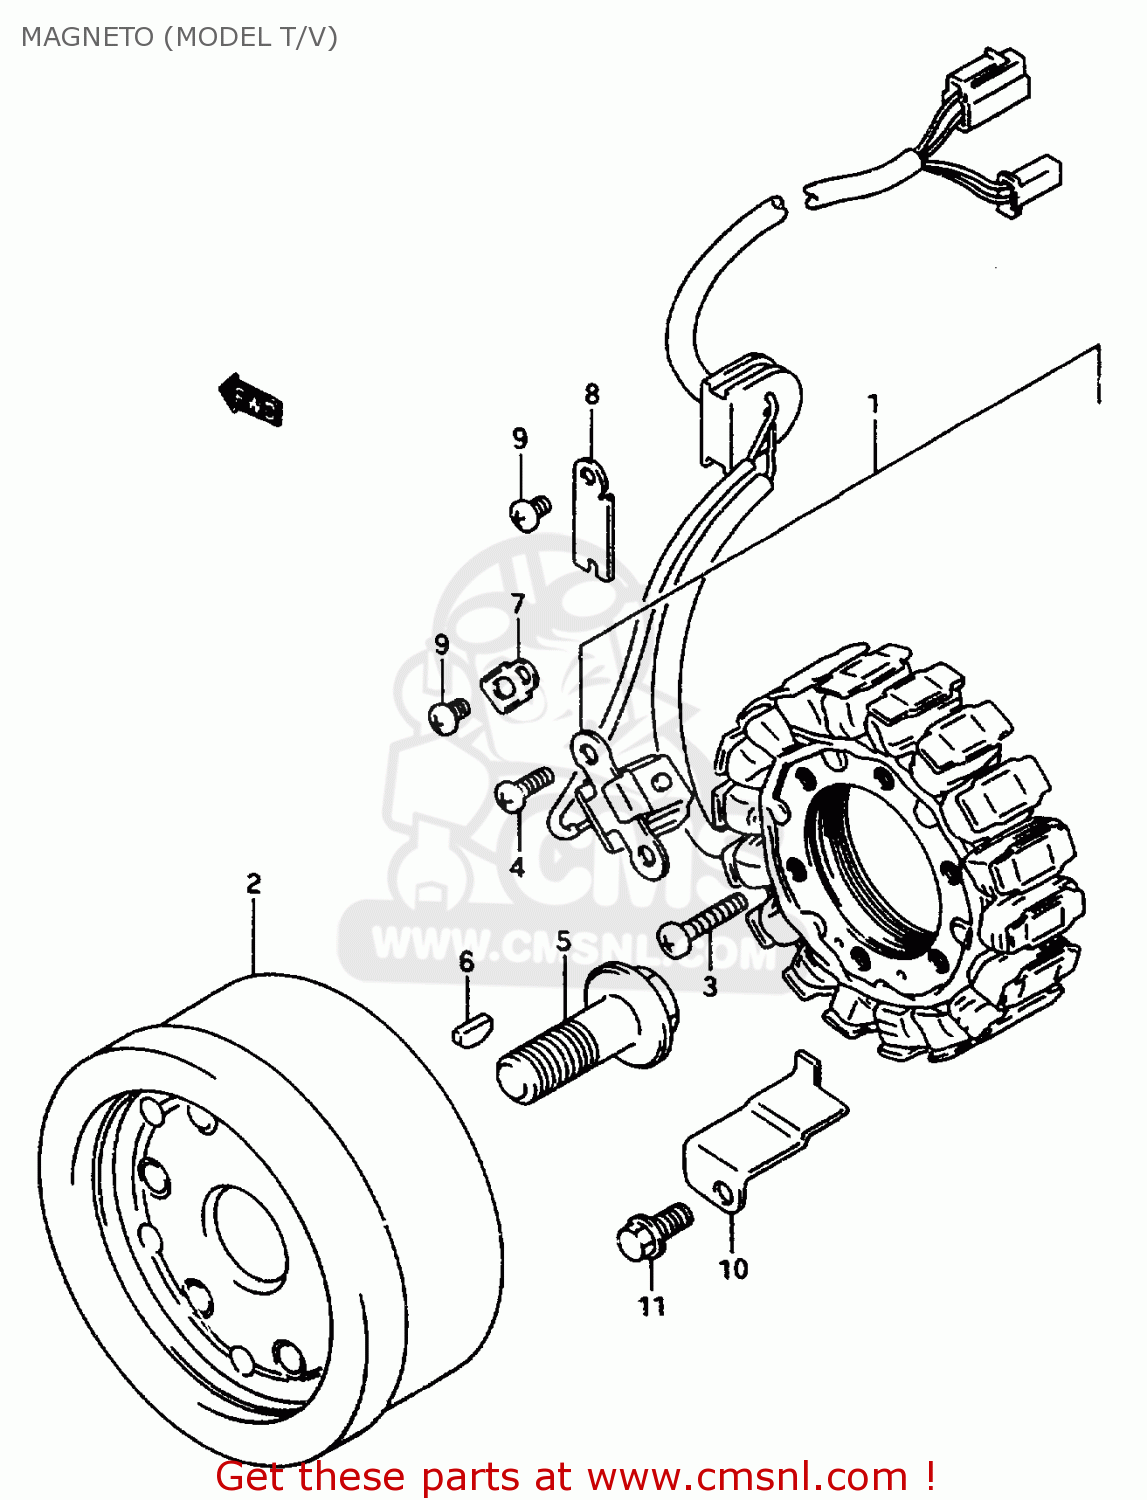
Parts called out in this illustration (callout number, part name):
1	STARTER ASSY
2	ROTOR ASSY
3	BOLT,G/S SWITC
4	SCREW
5	BOLT(14X43)
6	KEY
7	CLAMP,GENERATOR LEAD WIRE
8	CLAMP NO.1,MAGNETO READ WIRE
9	SCREW
10	SCREW
11	CLAMP,MAGNETO LEAD WIRE
12	BOLT
